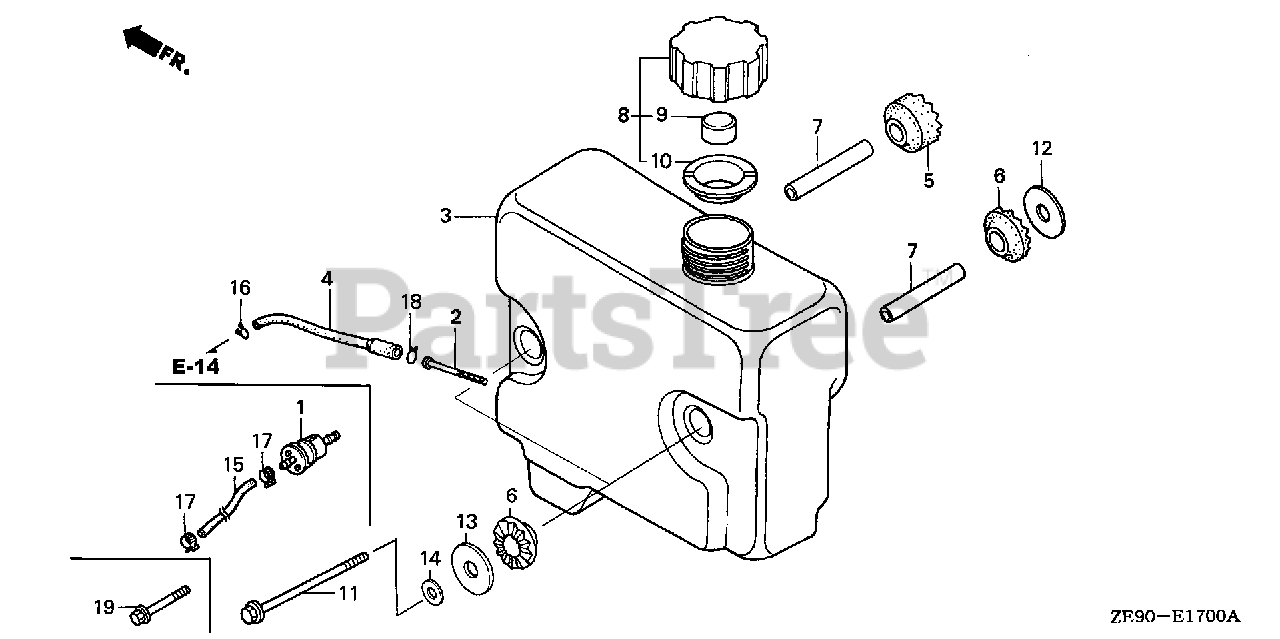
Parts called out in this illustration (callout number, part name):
1	FILTER, FUEL
15	BULK HOSE, FUEL (4.5X1000) (4.5X360)
17	CLAMP, TUBE (D8.5)
19	BOLT, FLANGE (8X16)
